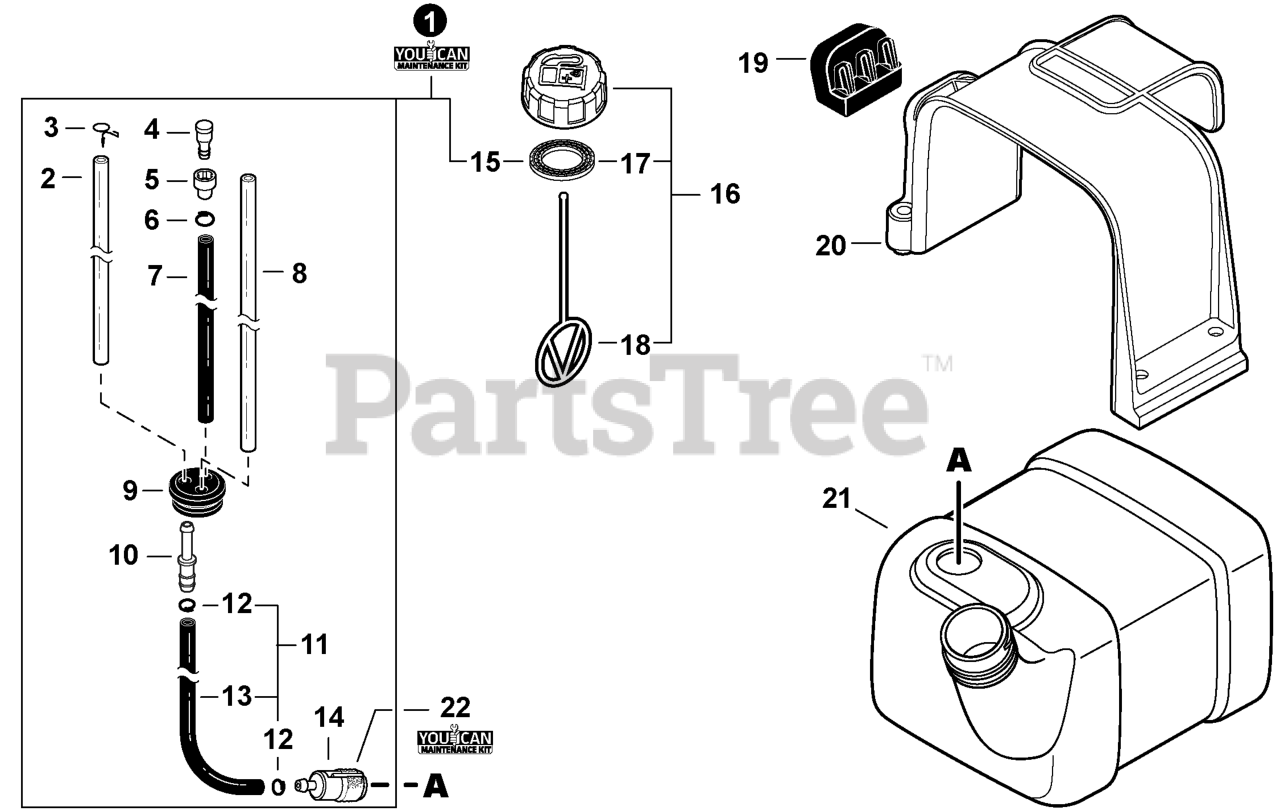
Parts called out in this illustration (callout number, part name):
1	FUEL SYSTEM KIT - YOUCAN
2	PIPE, FUEL 3.5x6x205 CLEAR
3	CLIP, SPRING 5.2
4	VENT ASSY
5	HOLDER, VENT
6	CLIP 6.5 MM
7	PIPE, FUEL 3x6x40 BLACK
8	PIPE, FUEL 3x6x180 YELLOW
9	GROMMET, FUEL
10	CONNECTOR, PIPE 5x3.5
11	KIT, FUEL PIPE, CLIPS
12	CLIP 6.5 MM
13	PIPE, FUEL 3x6x120 BLACK
14	FILTER, FUEL
15	GASKET, FUEL CAP
16	CAP ASSY, FUEL
17	GASKET, FUEL CAP
18	CONNECTOR, CAP L= 100 MM
19	CUSHION
20	RETAINER, FUEL TANK
21	TANK, FUEL
22	TUNE-UP KIT - YOUCANT
